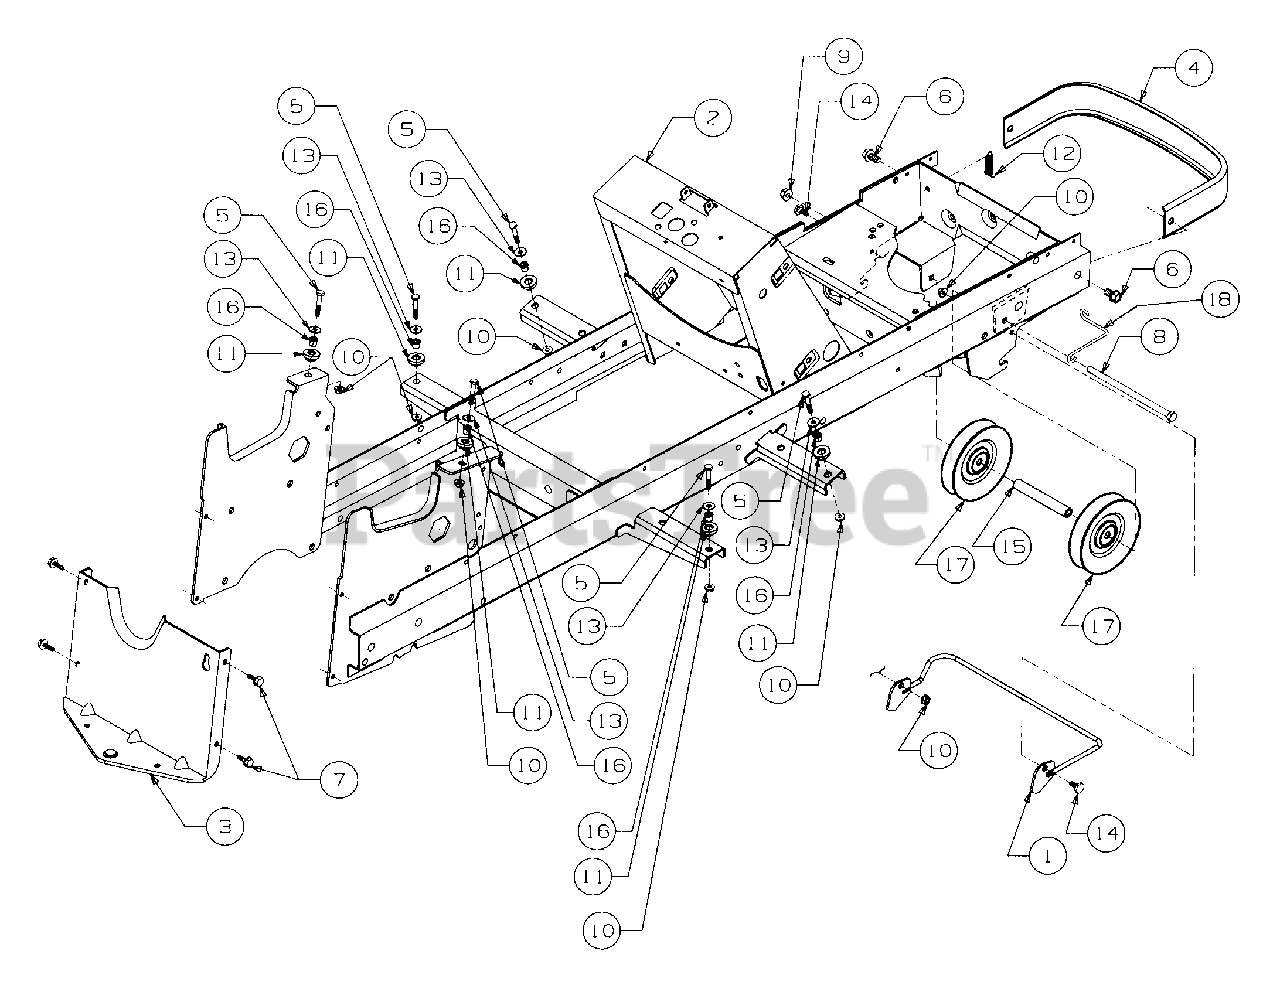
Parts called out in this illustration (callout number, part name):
1	Rod, Quick Attach
2	Frame
4	Bumper
5	Screw, Hex Cap, 1/4-20 x 1.0
6	Screw, Hex Wsh Hd Tapp 3/8-16 x .75
7	Screw, Hex Wsh Hd Tap 5/16-18 x .75
8	Screw, Hex Cap, 3/8-16 x 7.0
9	Nut, Hex Flange Lock, 3/8-16
10	Nut, Hex Flange Lock, 1/4-20
11	Grommet, Insulator
12	Spring, Latch
13	Washer, Flat, .255 x .72 x .60
14	Bolt, Shoulder
15	Spacer, Idler, .407 x .720 x 4.38
16	Spacer, .28 x .40 x .42 Lg
17	Pulley, Idler
18	Belt Guide
